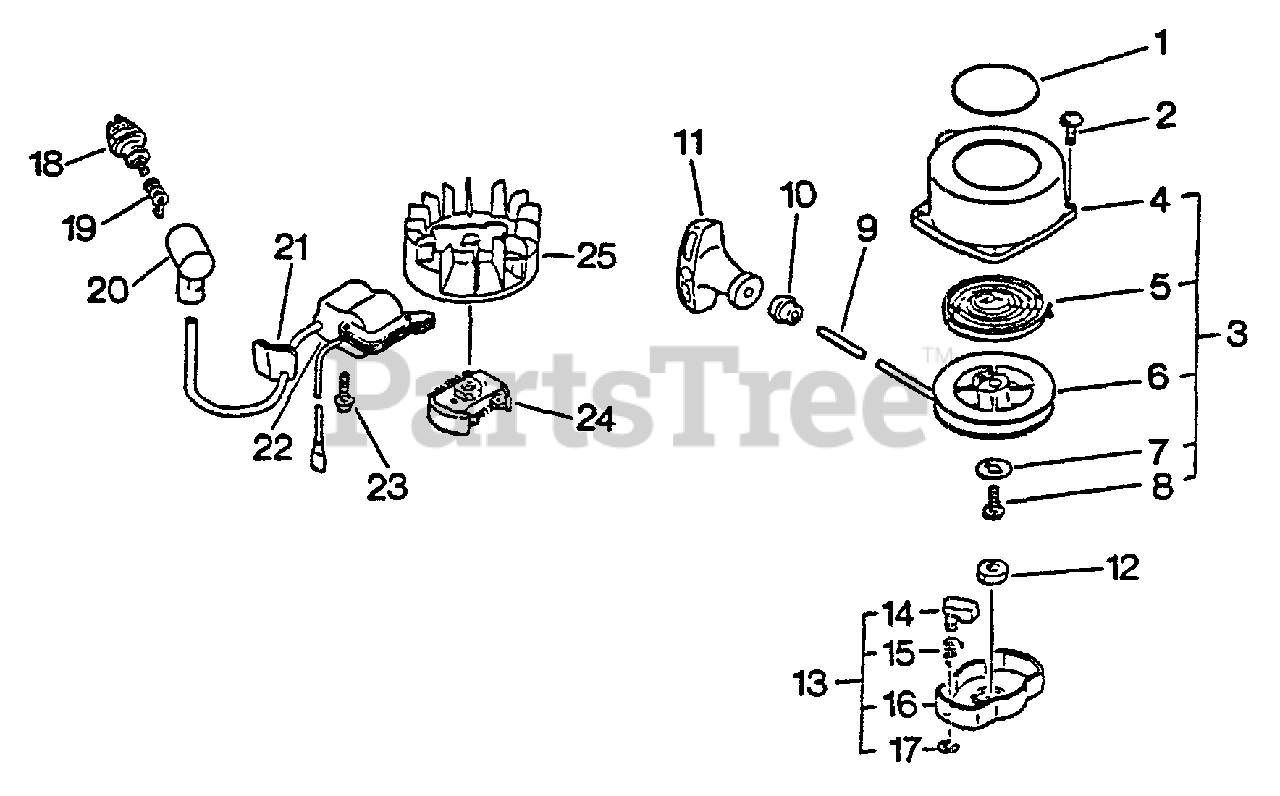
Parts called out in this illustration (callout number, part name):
1	LABEL - ECHO
2	SCREW - 4X16
3	STARTER ASSY
4	CASE, STARTER
5	SPRING, REWIND
6	REEL, ROPE
7	WASHER
9	ROPE, STARTER - 3X890
10	GUIDE, ROPE
11	GRIP, STARTER
13	STARTER PAWL ASSY
14	CATCHER, PAWL
15	SPRING, RETURN
16	PAWL, STARTER
17	RING, RETAINING - 4
18	SPARK PLUG -- CJ-8
19	TERMINAL, SPARK PLUG CAP
20	CAP, SPARK PLUG
21	COVER, DUST
22	COIL, IGNITION
23	SCREW - 4X22
24	CLUTCH ASSY
25	FLYWHEEL
